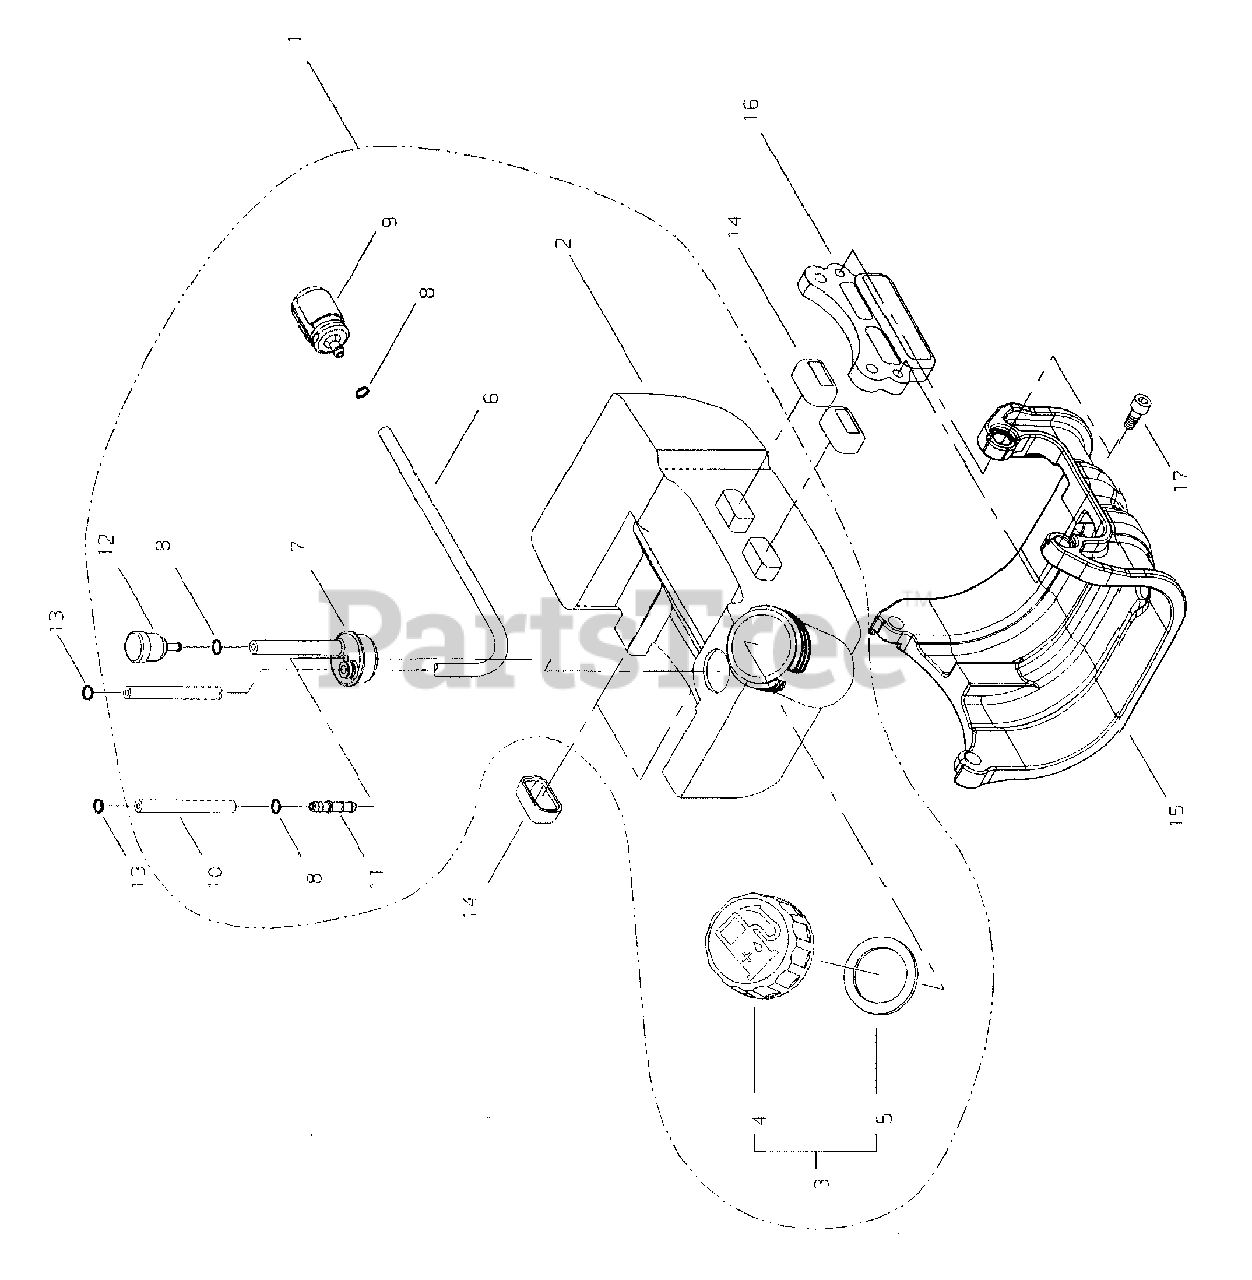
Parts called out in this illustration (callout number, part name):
1	FUEL TANK ASSY
2	TANK, FUEL
3	CAP ASSY
4	CAP, FUEL
5	GASKET, CAP
6	PIPE - FUEL
7	FUEL PIPE ASSY
8	CLIP - 6
9	FILTER, FUEL
10	PIPE - CLEAR
11	CONNECTOR, PIPE
12	VENT, FUEL TANK
13	CLIP - 6
14	CUSHION, FUEL TANK
15	GUARD, FUEL TANK
16	BRACKET, FUEL TANK
17	SCREW - 5X18
